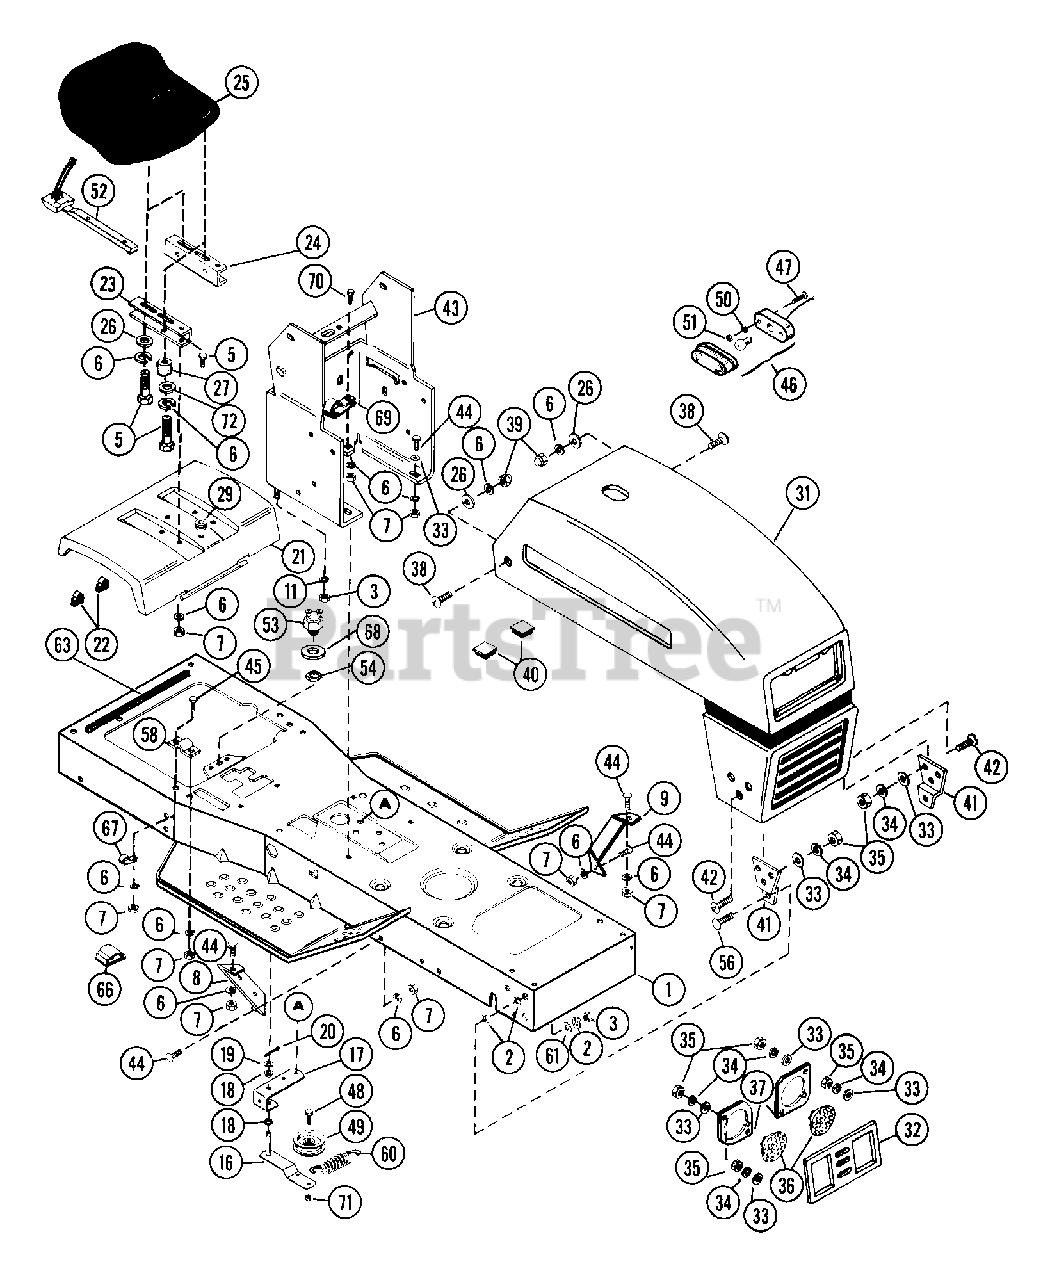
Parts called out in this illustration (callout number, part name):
1	FRAME W/DECALS
2	WSHR-LK .375X.094 MED PL
3	NUT-HEX .375-16
5	BLT-HEX .31-18X.75 PL GR5
6	WSHR-LK .312X.097 PL HVY
7	NUT-HEX .312-18
8	STRUT RIGHT FOOT BOARD
9	STRUT LEFT FOOT BOARD
10	BLT-RDHDSQNK .31-18X.75 GR5 PL
11	WSHR-LK .375X.115 HVY PL
16	IDLER ARM
17	IDLER PIVOT
18	BSHG-FLG .372X.500X.312X.625NY
19	WSHR-FL-STL.406X.812X.065PL
20	PIN-COTR .12X1.0 PL
21	REAR DECK
23	SEAT CHANNEL RH
24	SEAT CHANNEL LH
25	SEAT V-350
26	WSHR-FL-STL .38X.875X.083 PL
27	SPACER BUSHING .5 X .32 X .21
29	GROMMET, .31 ID
31	HOOD & GRILL W/DECALS YT8
31	HOOD & GRILL W/DECALS YT11
32	HEADLIGHT INSERT
33	WSHR-FL-STL.312X.734X.065PL
34	WSHR-LK .250X.077 HVY PL
35	NUT-HEX .250-20 PL
36	HEAD LIGHT
37	HEAD LIGHT RETAINER RING
38	SCR-MCH .31-18X.50 SLTR PL
39	NUT-CROWN .312-18 PL
40	STOP
41	HOOD HINGE
42	SCR-MCH .25-20X.75 SLTR PL
43	DASH BASE WITH DECALS
44	BLT-RDHDSQNK .31-18X.75 GR5 PL
45	BLT-HEX .31-18X.75 PL GR2
46	TAIL LIGHT
46	TAIL LIGHT LENS
47	SCR-MCH 10-24X.50 SLTR PL
48	BLT-HEX .38-16X1.50 PL GR5
49	IDLER-FLAT 2.75 X .38 DAYCO
50	WSHR-LK 10X.047 MED PL
51	NUT-HEX 10-24 PL
52	SWITCH SEAT
53	SWITCH-NEUTRAL START N.O.
54	NUT- .562-18
56	BLT-RDHDSQSHNK .38-16X1.00 PL
60	SG-TENS .080X.470X4.88 WLD 30
61	WSHR-FL-STL .438X1.0X.083 PL
62	WSHR-LK-EXT .313X.030 PL
63	1/4 X 3/4 X 1 IN FOAM TAPE
64	NUT-LK .375-16 PL
66	WIRE CLIP
67	J-CLAMP
68	WSHR-FL-STL .811X1.25X.005
70	BLT-RDHDSQNK .31-18X1.00 PL
71	NUT-LK TOP .375-16 GR C YWZC
72	WSHR-FL-STL .505X.875X.024 PL
